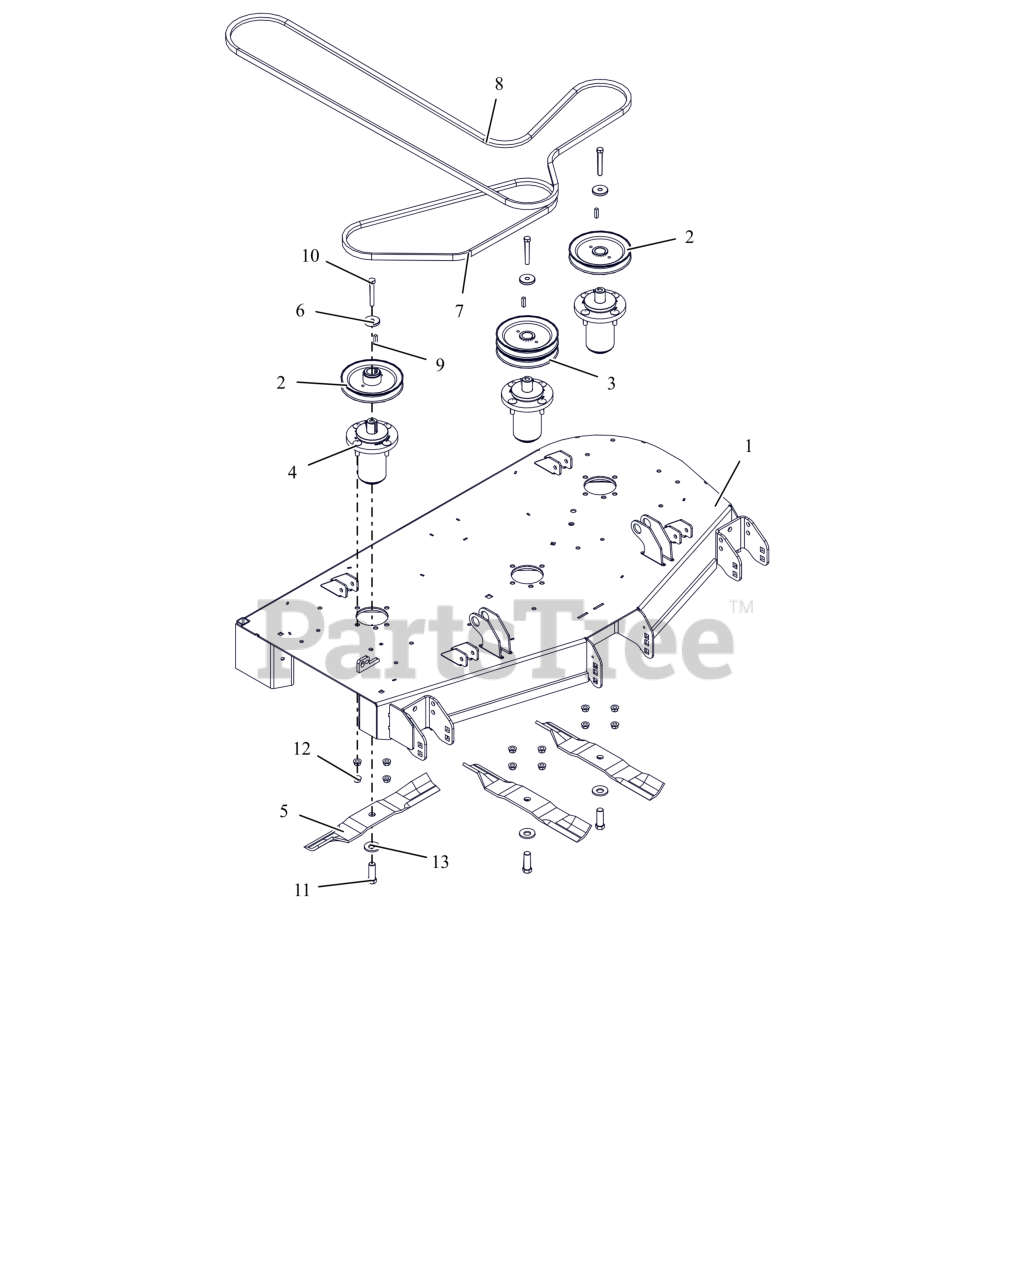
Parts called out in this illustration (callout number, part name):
1	KIT,DECK-48" W/DECALS-GRAVELY
2	PULLEY, SINGLE-1"ID X 6" OD
3	PULLEY, DOUBLE
4	ASM, MAINT FREE ALUM SPINDLE
5	BLADE, 16.19" MOWER (HI-LIFT)
6	RETAINER, SHEAVE
7	V-BELT, B-COGGED
8	V-BELT, HB SECTION
9	KEY, SQ .25X.25X1.00 RC 40-50
10	BLT, HEX .38-16X2.75 G8 ZCC
11	BLT, HEX .62-18X1.75 G8 ZCC
12	NUT-LK-CTR-FLG .375-16 GF ZCC
13	WSHR-BLVL .669X1.535X.138
